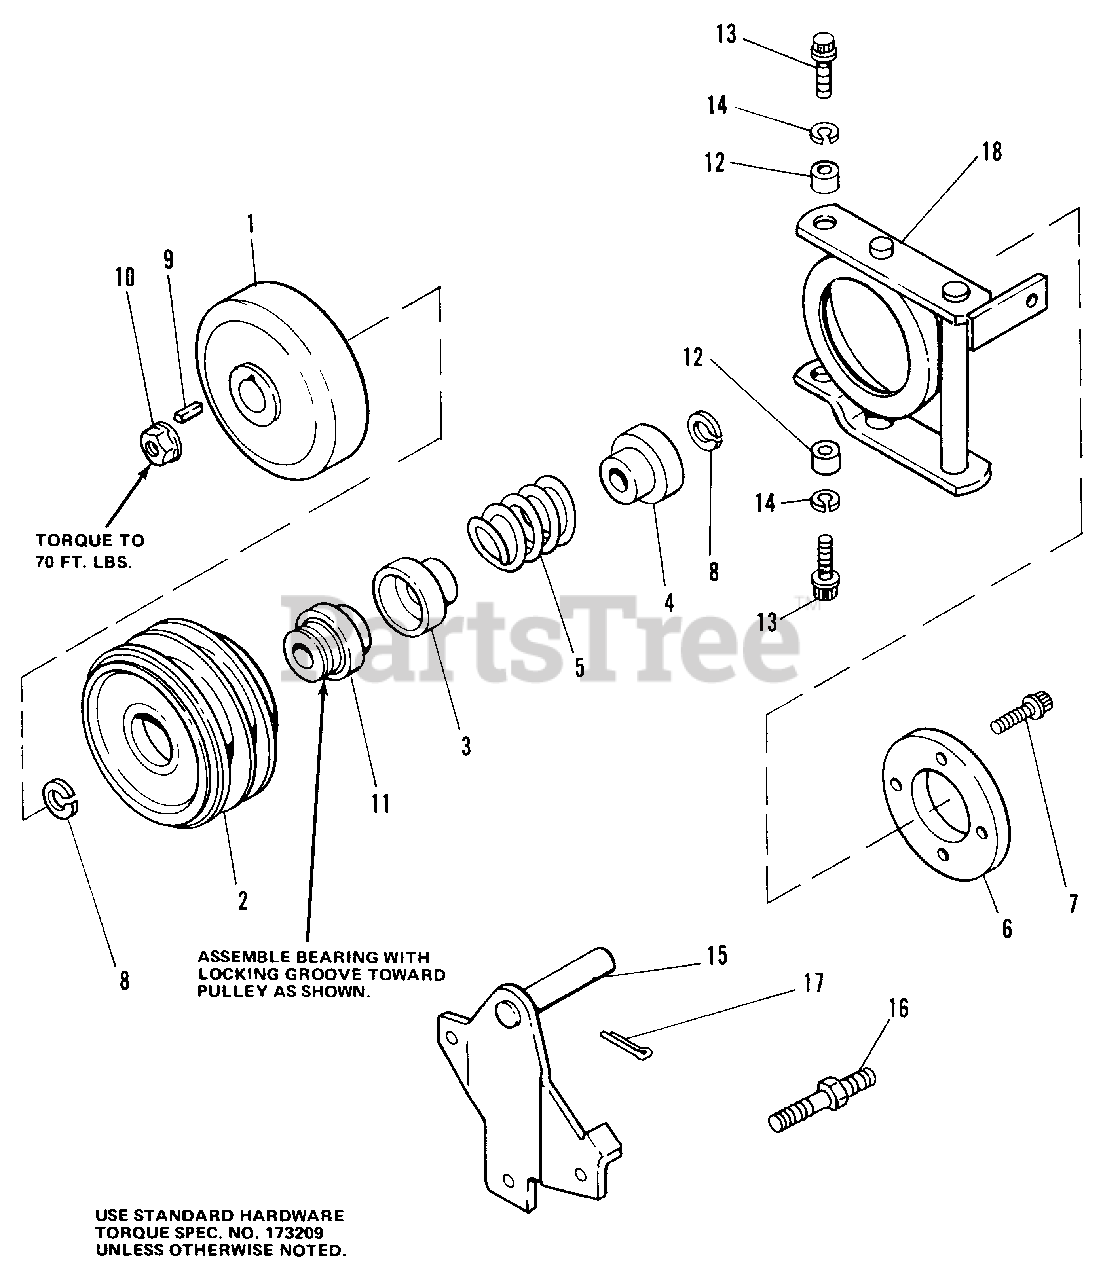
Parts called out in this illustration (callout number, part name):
1	CLUTCH PLATE ASSEMBLY
3	GUIDE, Spring
4	GUIDE, Spring
6	DISC, Brake
7	CAPSCREW, Skt. Hd., 1/4-20 x 5/8
8	RING, Retaining
9	KEY
10	LOCKNUT, Flange, 3/4-16
11	BEARING ASSEMBLY
13	SCREW, Thd. Forming
14	LOCKWASHER, 5/16
15	PIVOT ARM ASSEMBLY
17	PIN, Cotter, 3/16 x 1-1/2
18	PIVOT ASSEMBLY
